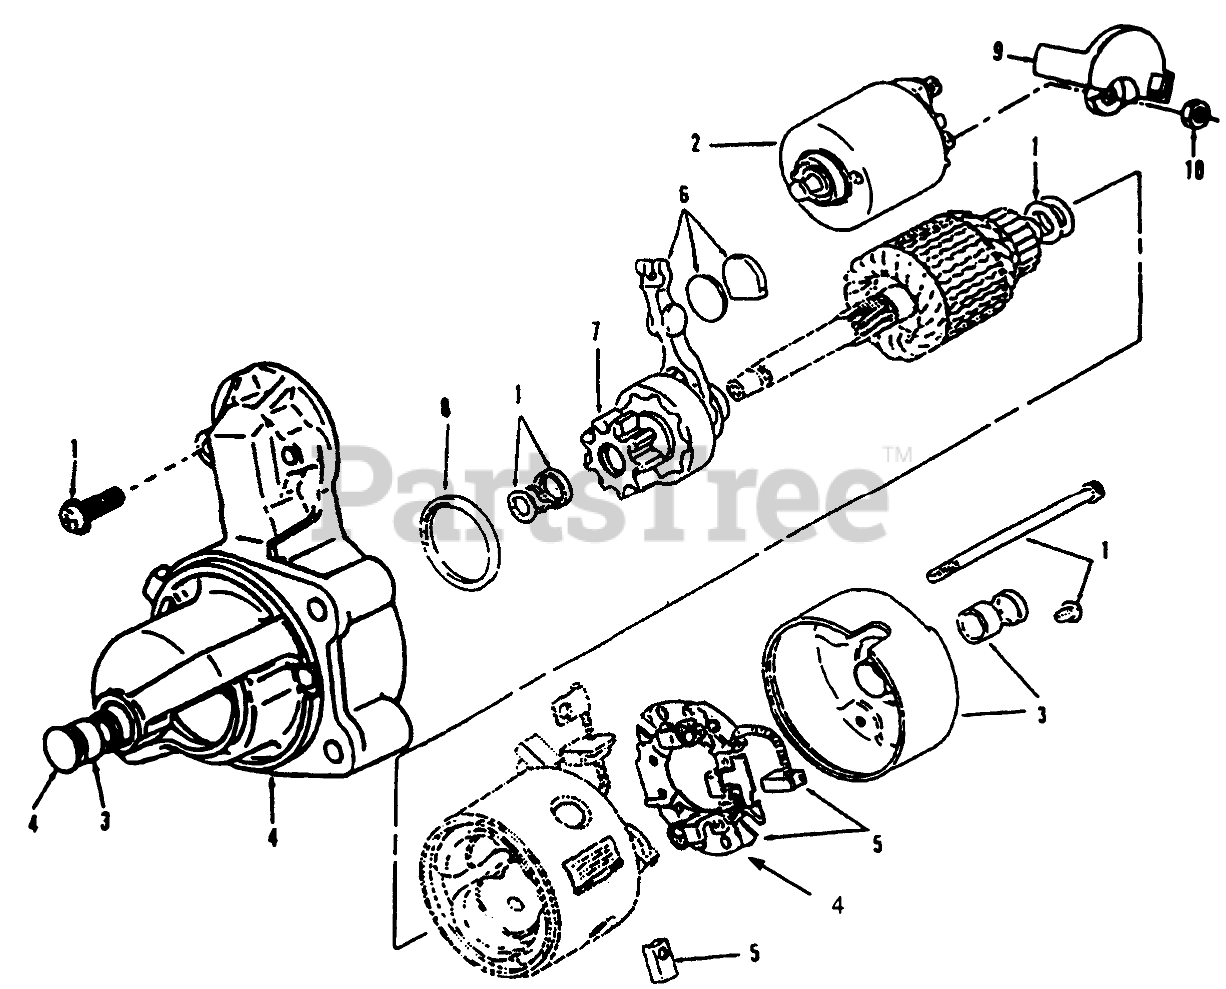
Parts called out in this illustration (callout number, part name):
1	Kit-Hardware, Starter (Includes (2) Solenoid Mtg Screws, 2 Thru Bolts, Armature Shims, Pinion Collar, & Retaining Ring)
2	Kit-Solenoid, Starter (Includes Solenoid & Spring Plunger)
3	Kit-Bushing, Starter (Includes Rear Cap with Bushing & Front Bushing)
4	Kit-Mounting Bracket (Incl. Ref. #5)
5	Kit-Brush, Starter (Includes (2) Negative & (1) Positive Brushes)
6	Kit-Shift Lever, Starter (Includes Lever, Wear Plate & Rubber Plug)
7	Clutch Assembly-Starter (Includes Pinion Gear)
8	Dust Seal
9	Cap-Starter Solenoid
10	Nut-M8
